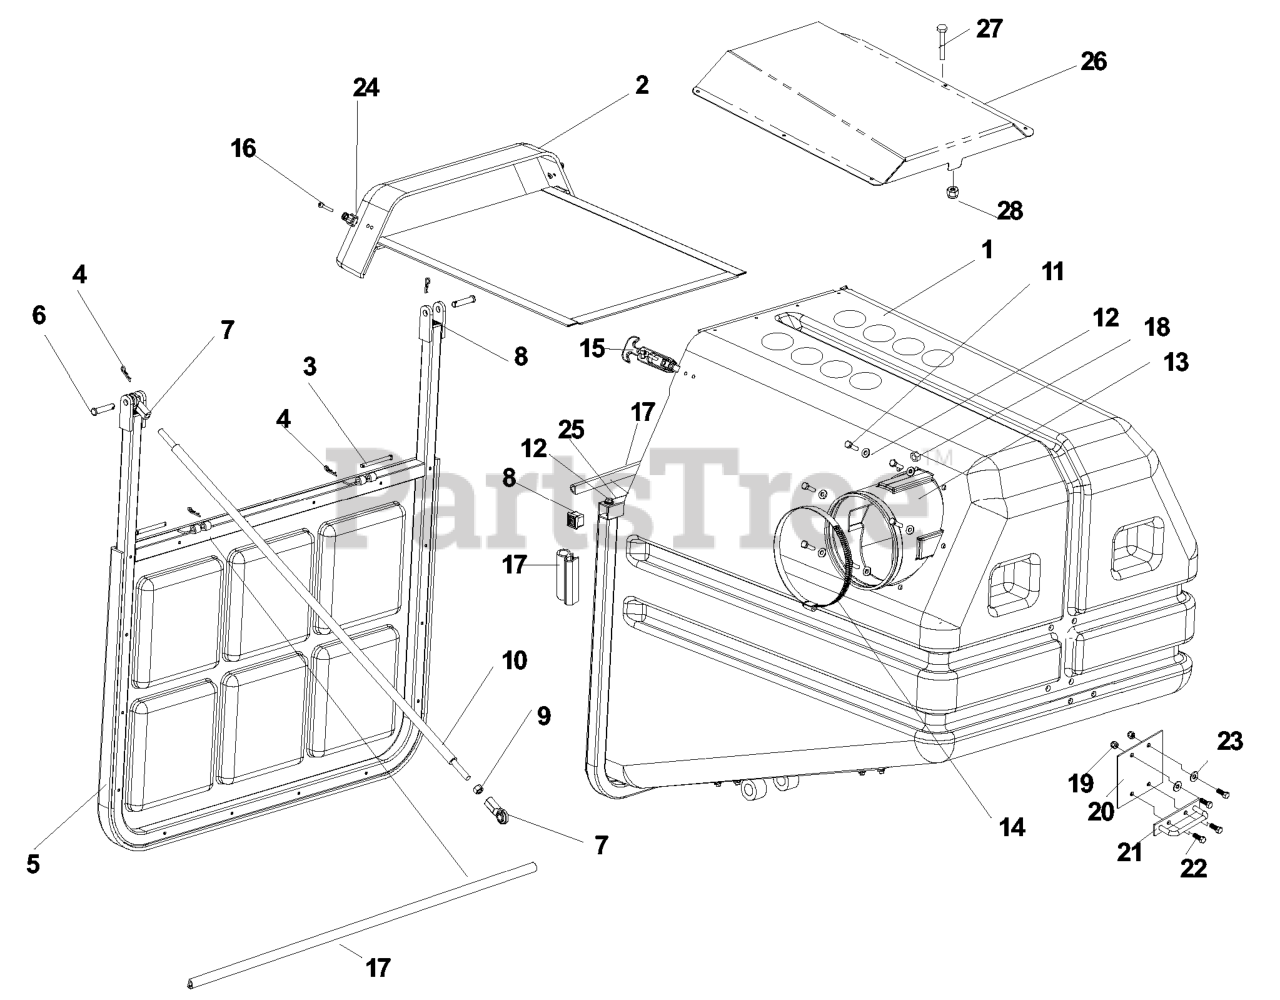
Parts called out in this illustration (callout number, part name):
1	CONTAINER ASM.
2	EXHAUST ASM.
3	CLEVIS PIN
4	PIN, HAIR COTTER #13 5/64 X 1
6	PIN
7	ROD END
8	FINISHING PLUG
9	HEX NUT 3/8-24
10	PAINTED ARM BLACK
11	BOLT, 1/4-28 X 1
12	WASHER, 1/4
14	HOSE CLAMP
16	PANHEAD SCREW
17	SVC KIT, DOOR SEAL
18	NUT, 1/4-20, NYLOC
19	NUT 3/8 NYLOC
20	BACK PLATE
21	CONTAINER LATCH WELDMENT BLACK
22	BOLT, 3/8-16 X 1
23	WASHER, 3/8
24	LATCH BASE
25	BOLT 1/4-20 X 2"
27	SCR #10-24 X 3/4
28	NUT 10-24 NYLOC
